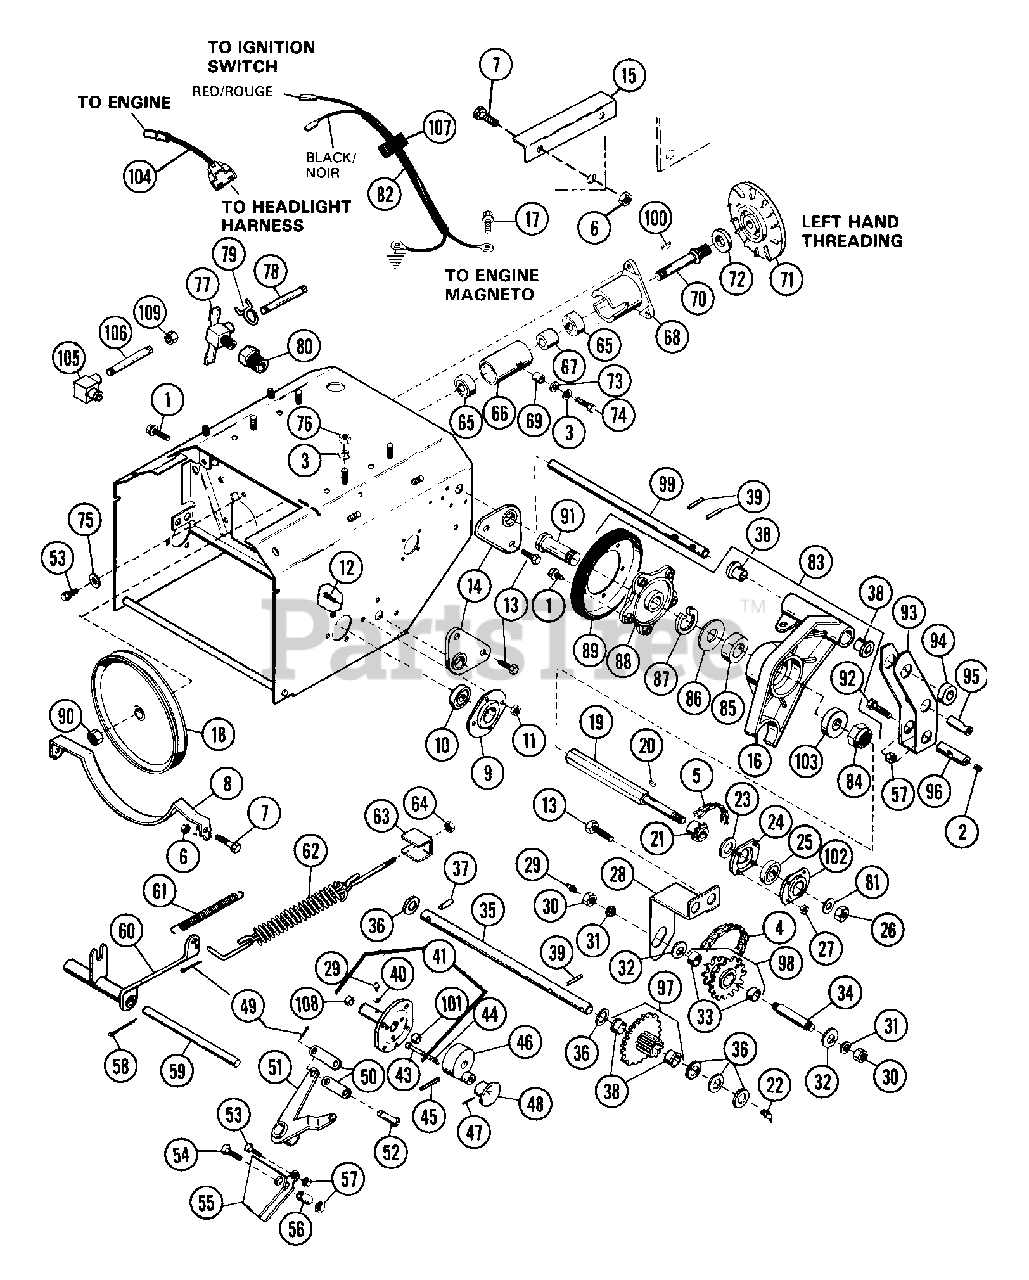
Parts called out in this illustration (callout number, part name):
1	BLT-SERHFWH .31-18X.50 PL
2	SCR-SET .32-18X.38 SKHCUPNL OH
3	WSHR-LK .312X.097 PL HVY
4	PINION CHAIN
5	IDLER CHAIN
6	NUT-LK-CTR .250-20 PL
7	BLT-HEX .25-20X.50 PL GR2
8	BELT RETAINER
9	BEARING RETAINER
10	BRG-BALL 1.13X2.18X.63
11	NUT-LK-FLG .250-20 PL
12	BLT-SERNK SL .25-20X.50 PL
13	BLT-SERHFWH .25-20X.50 PL
14	SUPPORT, SHAFT
16	CARRIER
17	SCR-TAP .250-20X.37 HWH PL TR
18	PLY-V 8.00 X 1.0 W/KEY CLARK
19	HEX SHAFT
20	KEY-WDRF .125X.625X.250 SAE5
21	9 TOOTH SPROCKET
22	HYDRAULIC DRIVE FITTING
23	WSHR-FL-STL .505X1.000X.062
24	BEARING FLANGE
25	BRG-BALL .500X1.38X.437
26	NUT-LK-CTR .50-20 PL
27	NUT-LK DUAL FACE 10-24 PL
28	SUPPORT, SHAFT
29	SPIN DRIVE ZERK FITTING
30	NUT-HEX .375-16
31	WSHR-LK .375X.130
32	WSHR-FL-STL .382X.812X.062
33	BSHG-SLV .500X.625X.500 BR
34	REDUCTION SHAFT
35	PINION SHAFT
36	WSHR-FL-STL .630X1.005X.062 PL
37	PIN-ROLL .125X1.00
38	BSHG-FLG .625X.750X.500X.875BR
39	PIN-ROLL .156X1.00
40	WSHR-LK .250X.047 LT PL
41	L H AXLE ASSEMBLY
44	SG-COMP .028X.34X1.062 WLD75
45	PIN-GRV .250X1.75 TP C
46	LOCKOUT HUB
47	PIN-ROLL .093X1.00
49	PIN-COTR .09X.75 PL
50	SHIFT LINK
51	LEVER - SHIFT ARM
52	CLEVIS PIN
53	BLT-HEX .31-18X.50 PL GR2
54	BLT-HEX .31-18X3.00 PL GR2
55	BRACKET SHIFT LEVER
56	SPACER .5 X .33 X 2.4
57	NUT-LK .312-18 GR A PL
58	PIN-COTR .09X1.0 PL
59	ROD, FORK PIVOT
60	FORK, CLUTCH
61	SG-TENS .080X.73X3.06 WLD 20
62	SPRING ASSEMBLY
63	ADAPTER SPACER
64	NUT-LK-NYL.312-18 PL
65	BRG-BALL .625X1.375X.44
66	SPINDLE HOUSING
67	BEARING SPACER
68	DRIVE SPINDLE HOUSING
70	SPINDLE
71	DRIVE PLATE
72	DRIVE DISC SPACER 1.3X.76X.19
73	WSHR-FL-STL.344X.688X.065PL
74	BLT-HEX .31-18X1.00 PL GR 2
75	WSHR-LK-INT .313X.030 PL
76	NUT-HEX .312-18
77	DRAIN LOCK
78	TUBE
79	HOSE CLAMP
80	BUSHING
81	WSHR-FL-STL .531X1.062X.095 PL
82	SHORTING WIRE
83	FRICTION WHEEL ASSEMBLY
84	NUT-LK-NYL .875-14
85	BRG-BALL .876 X 1.750 X .50
86	WSHR-FL-STL .880X1.250X.062
87	RG-RTNG-INT 1.750X.062
88	SPINDLE HUB
89	FRICTION DISC
90	NUT-LK-NYL.625-18 PL
91	SPINDLE HUB
92	BLT-HEX .31-18X.75 PL GR2
93	CLUTCH ENGAGEMENT YOKE
94	SPACER 1.00 X .64 X .38
95	ADAPTER
96	ROD ADAPTER
97	PINION & SPROCKET ASSEMBLY
98	SPROCKET ASSY
99	CARRIER SHAFT
100	KEY-WDRF .125X.500X.203 SAE 3
101	BSHG-SLV .562X.625X.625 BRZ
102	BEARING FLANGE
103	BSHG-SLV .882X1.250X.531
105	STREET ELBOW
106	NIPPLE
107	WIRE CLIP
108	BSHG-SLV .750X.814X .750 BRZ
109	HEX CAP
